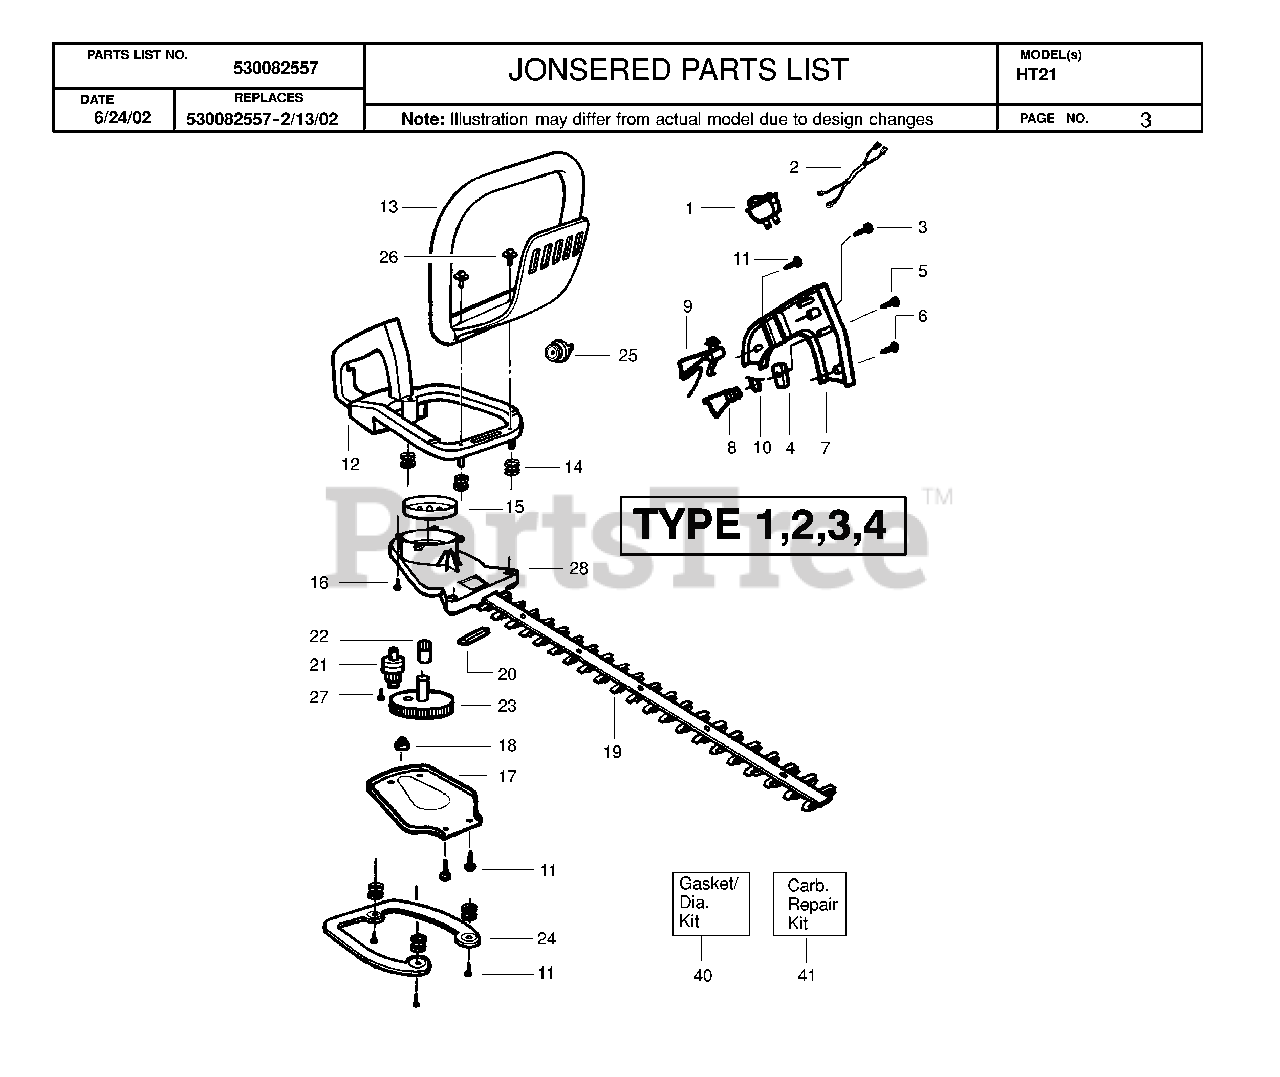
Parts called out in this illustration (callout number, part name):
3	SCREW 8-16 X 9/16 (PLAS
6	SCREW-10-16 X 1-3/8 PLA
9	LOCKOUT-THROTTLE
14	ANTIVIBE MOUNT
15	CLUTCH DRUM
16	SCREW-10-14 X 13/16 (PL
17	PLATE-GEARBOX COVER
18	BLADE BUSHING
19	BLADE ASSEMBLY
24	ISOLATOR PLATE
25	FUEL CAP ASSY W/RET.
27	SCREW-10-16 X 1/2, TYPE 2
28	GEARBOX ASSY
